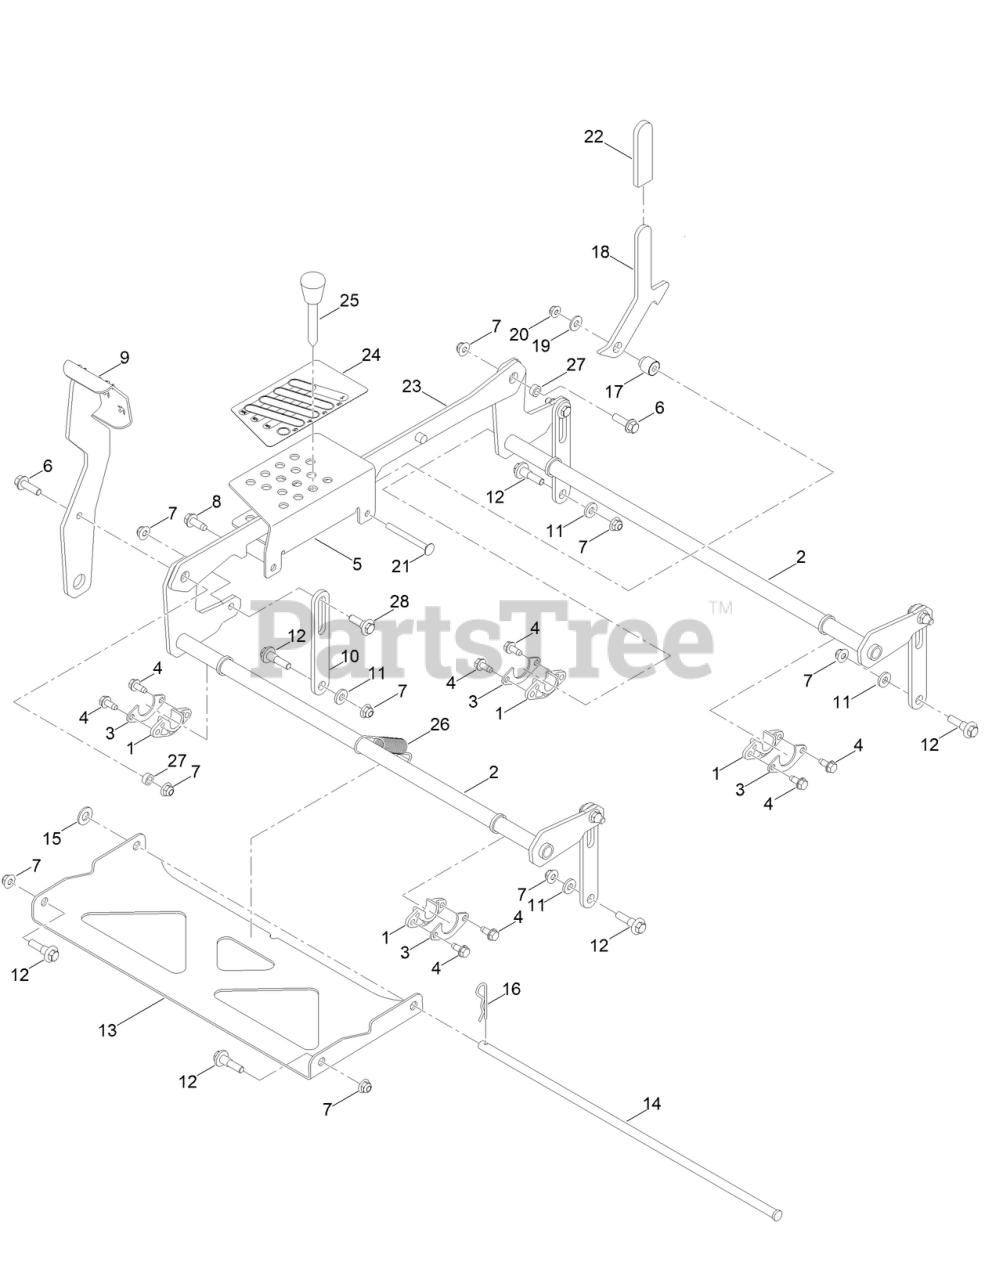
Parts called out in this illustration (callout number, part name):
1	BEARING-FLANGE
3	GUSSET-DECK LIFT
4	SCREW-HWHTF
5	BRACKET-HOC
6	SCREW-HHF
7	NUT-HF, NI
8	SCREW-HWH
11	SPACER-HUB, BLOWER
12	BOLT-SHOULDER
13	PAN-DECK PIVOT
14	PIN-DECK
15	WASHER-FLAT
16	PIN-HAIR
17	SPACER-STEPPED
18	PLATE-TRANSPORT LOCK
19	WASHER-PLAIN
20	NUT-HF
21	SCREW-CARR
22	GRIP-HANDLE
24	DECAL-HOC
25	HOC PIN ASM
26	SPRING-EXTENSION
27	SPACER
28	SCREW-SHOULDER, HWH
